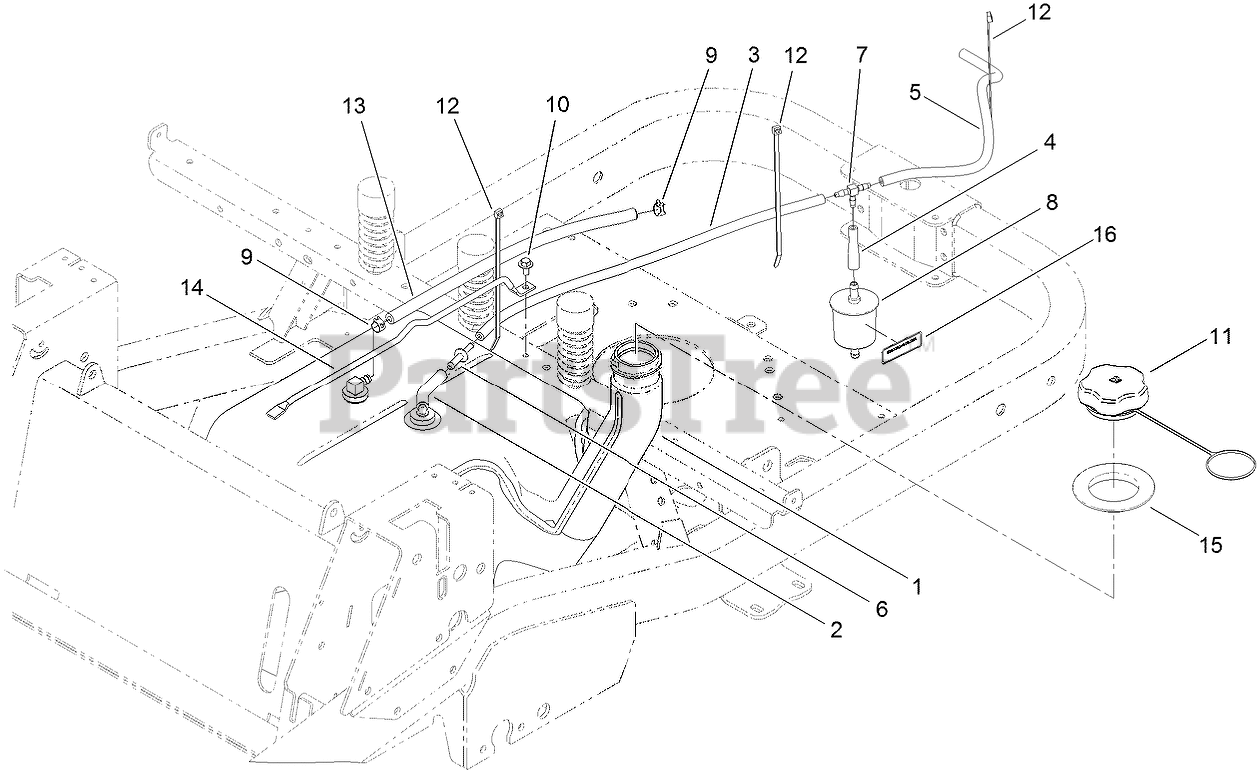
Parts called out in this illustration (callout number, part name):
1	FUEL TANK ASM
2	HOSE-FUEL
3	HOSE-FUEL
4	HOSE-FUEL, MOLDED
5	HOSE-FUEL
6	ADAPTOR-ORIFICE
7	FITTING-TEE
8	FILTER-FUEL
9	CLAMP-HOSE
10	SCREW-HHFTF
11	CAP-FUEL, RACHETING
12	TIE-CABLE
13	HOSE-FUEL
14	ROD-TANK, GAS
15	SEAL-TANK
16	DECAL-FILTER, EMISSIONS
